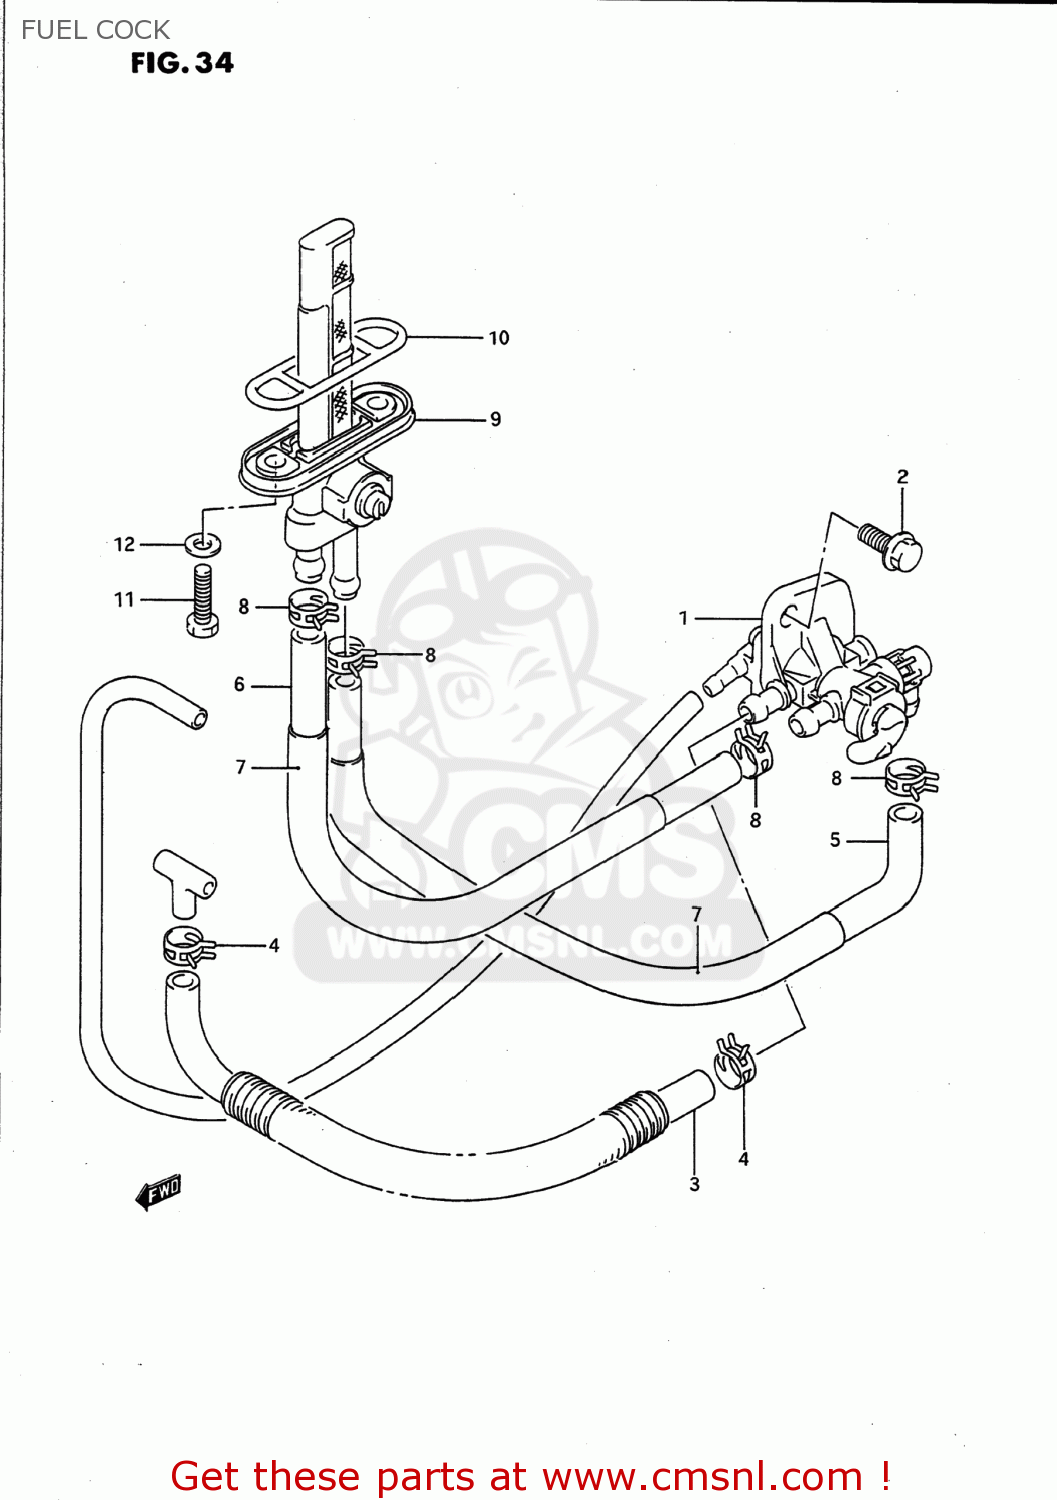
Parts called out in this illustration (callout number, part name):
1	COCK ASSEMBLY,FUEL
2	BOLT
3	HOSE(7X11X600)
4	CLIP
5	HOSE(7X11X600)
6	HOSE,FUEL RESERVE
7	PROTECTOR,FUEL HOSE
8	CLIP
9	COCK ASSY,FUEL NO.1
10	O RING,FUEL COCK
11	BOLT(6X20)
12	GASKET(6.4X11.5X0.8) (NAS)
